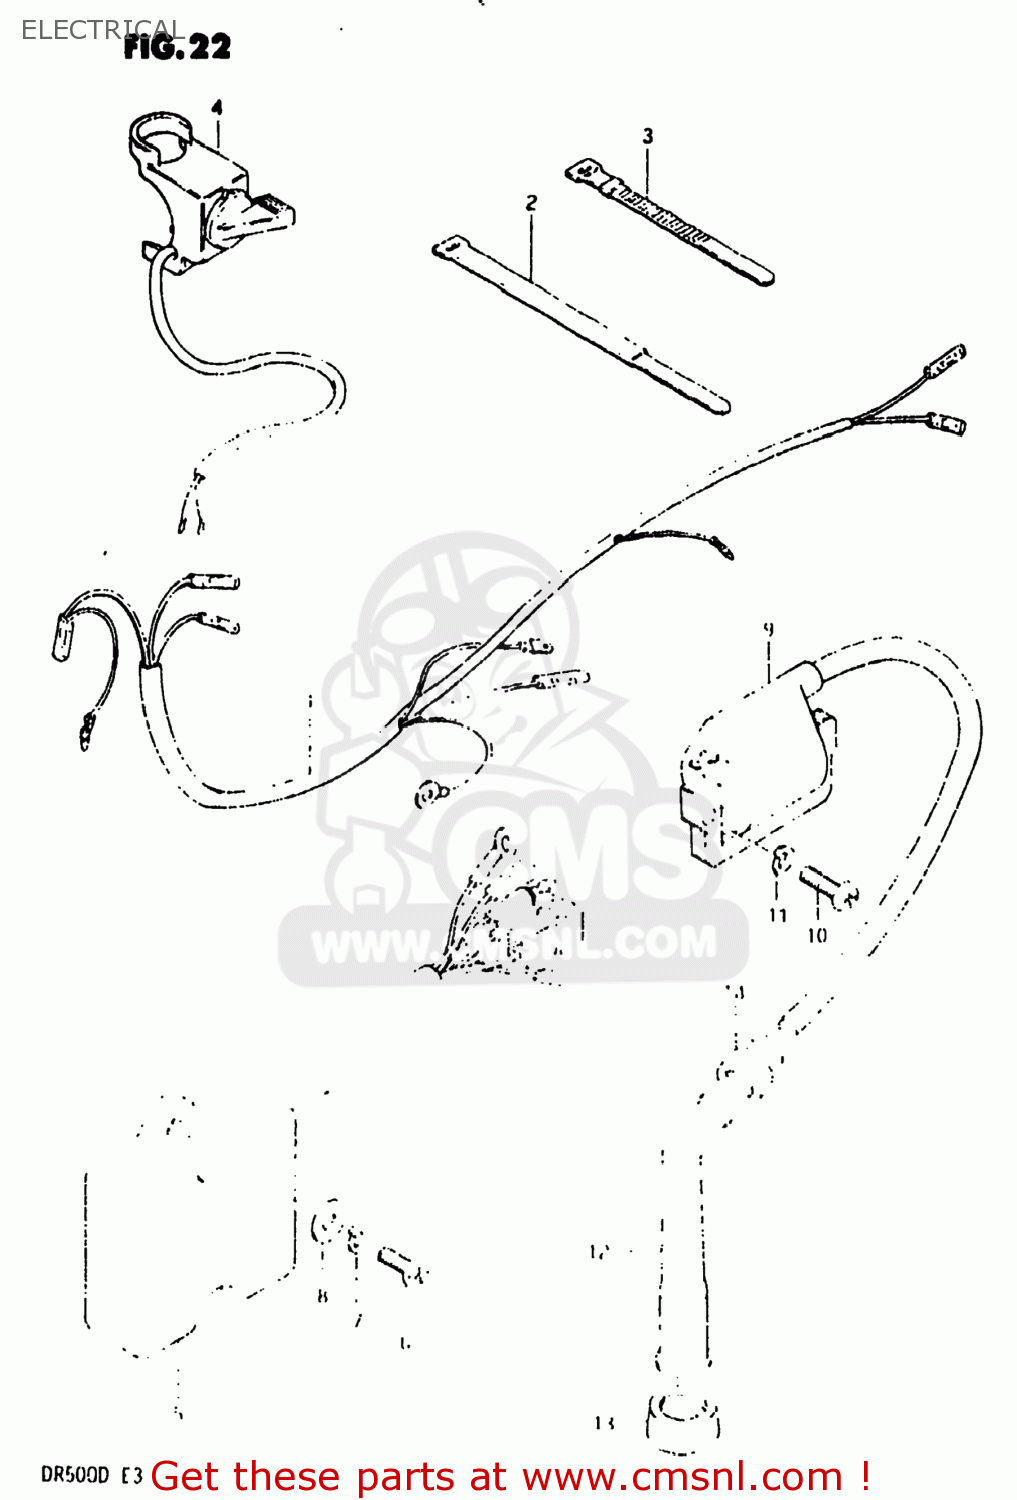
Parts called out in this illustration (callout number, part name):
1	HARNESS,WIRING
2	CLAMP
3	CLAMP(L:120)
4	SWITCH ASSY,ENGINE STOP
5	CDI UNIT
6	SCREW
7	LOCK WASHER
8	WASHER (6.5X18X1.6)
9	COIL ASSEMBLY,IGNITION
10	SCREW
11	LOCK WASHER
12	CAP ASSY,SPARK PLUG
13	SEAL,SPARK PLUG
14	SEAL,SPARK PLU
